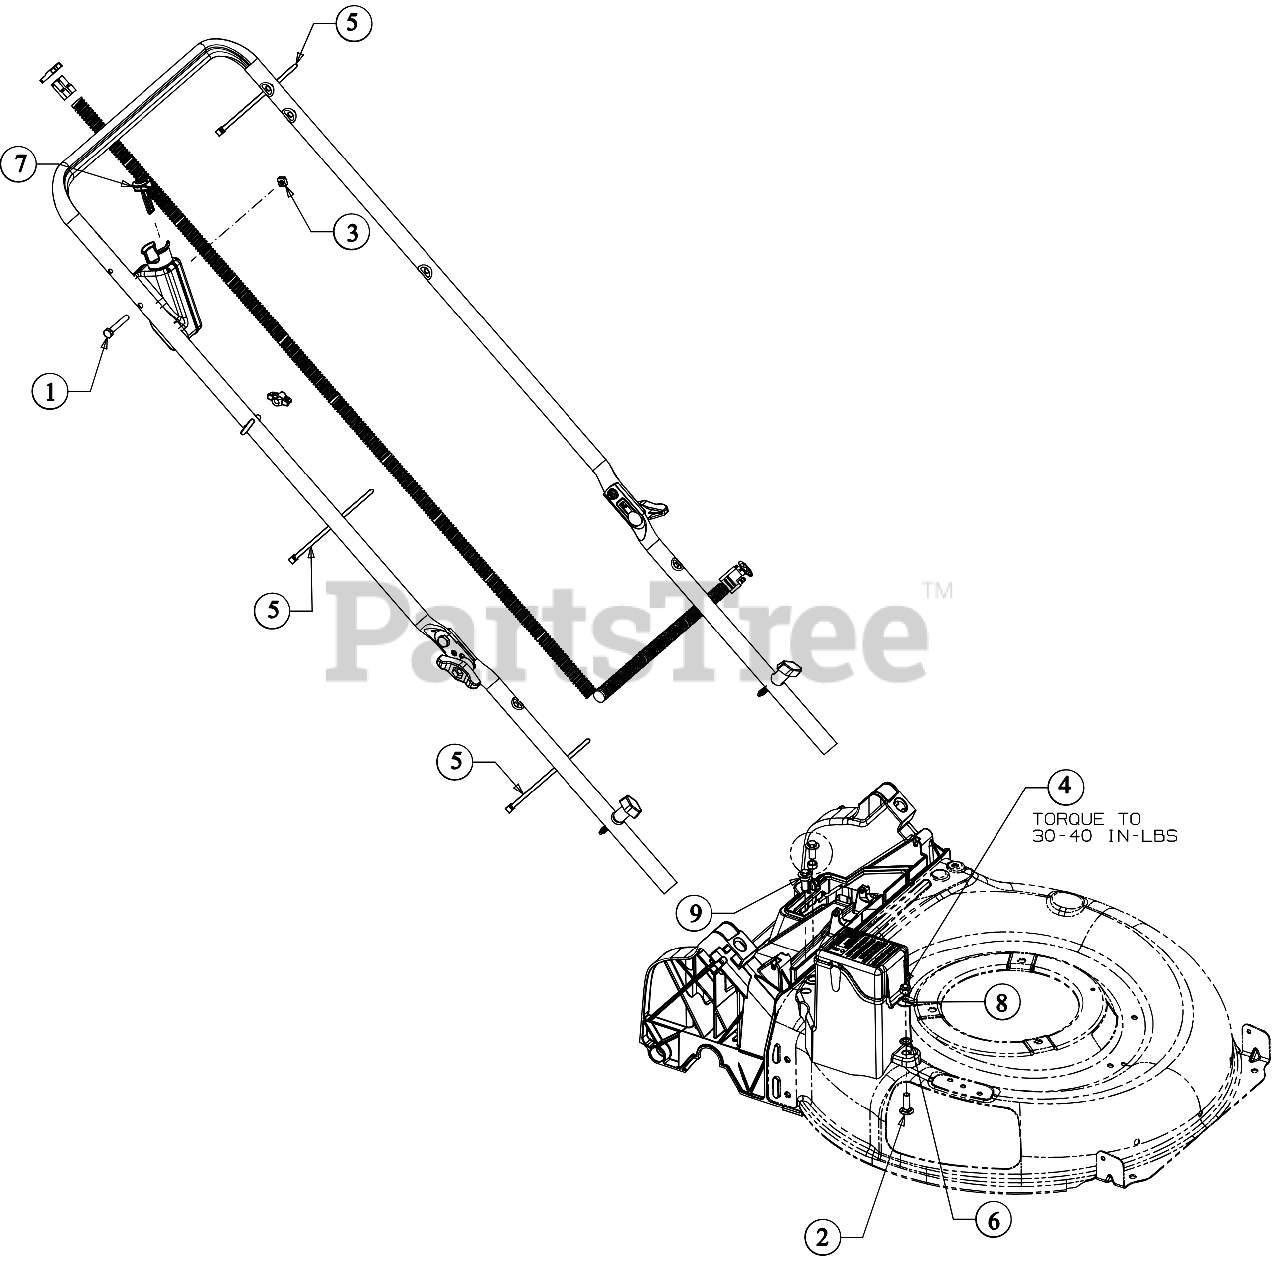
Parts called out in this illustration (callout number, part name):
1	HEX SCREW 1/4-20 X 1.75
2	CARRIAGE BOLT 5/16-18 X 1.00
3	SQUARE NUT 1/4-20
4	HEX NUT
5	CABLE TIE 7"
8	BELL WASHER .337 X.867 X .057
9	SHOULDER SCREW 5/16-14 x .972
